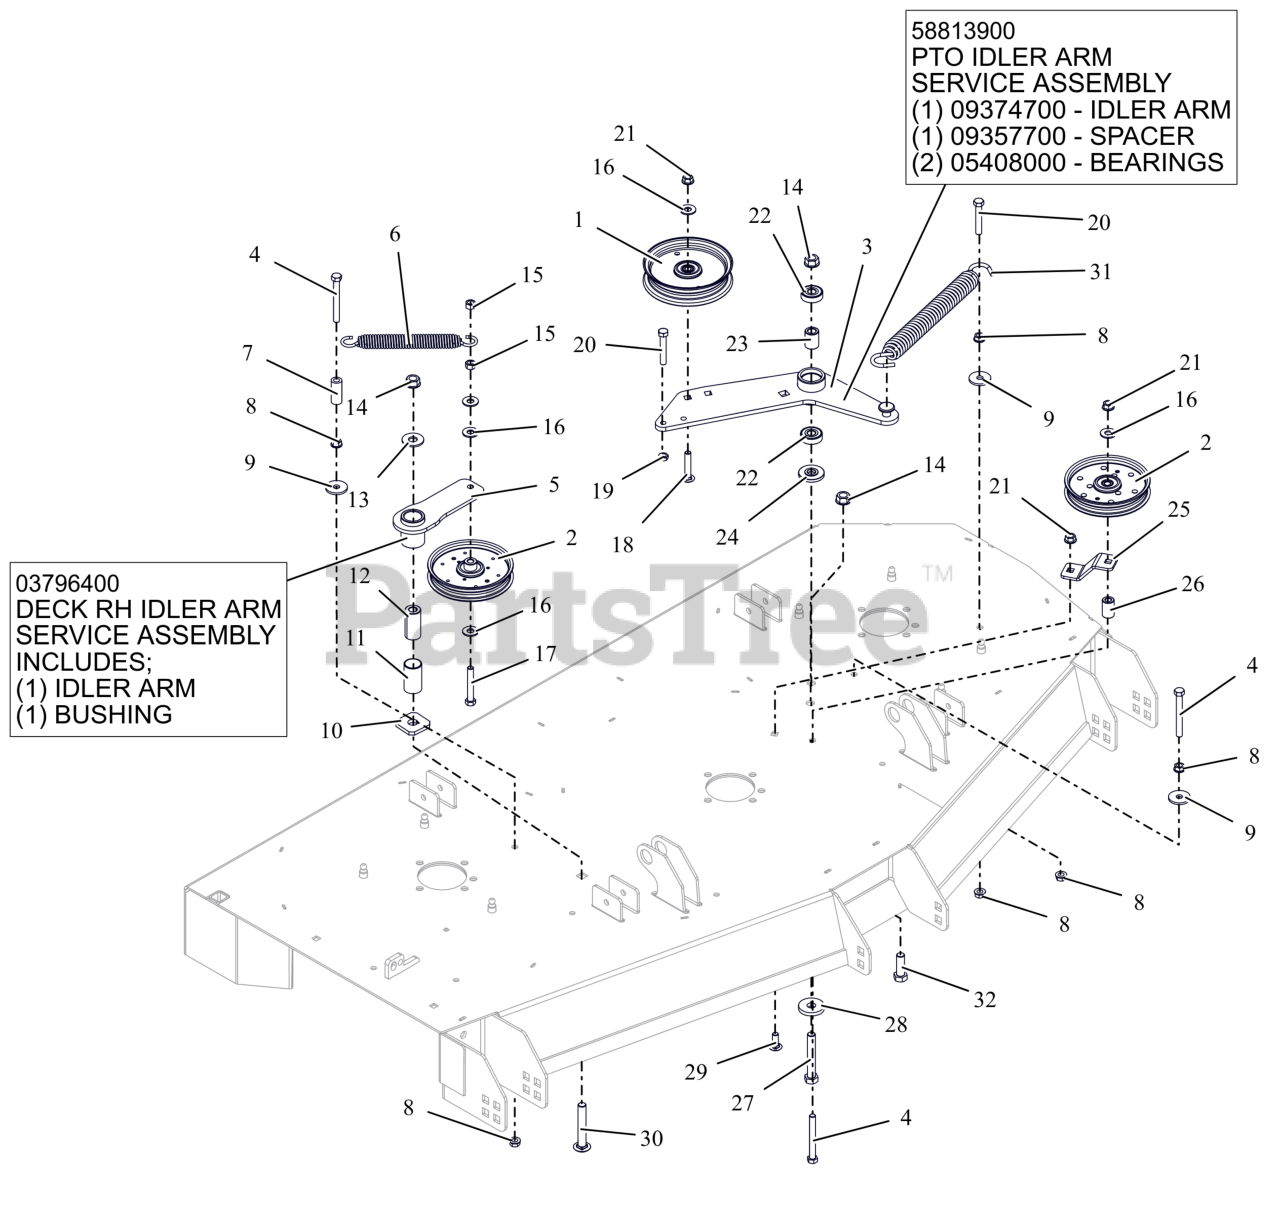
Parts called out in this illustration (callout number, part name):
1	IDLER- FLAT - 5.00" X .75"
2	IDLER- 5" FLANGED
3	PTO IDLER ARM
3	WLDMT, IDLER ARM PT660
3	SPACER .510 X .867 X 1.1485
3	BRG-BALL .500X1.38X.437
4	BLT, HEX .38-16X3.25 G5 ZCC
5	ASM, IDLER ARM (DECK)
5	WMT, IDLER ARM - BLACK
5	BSHG, 1.00X1.125X1.937
6	SPRING- EXTENSION
7	HOSE, .38 X 1.65
8	NUT, SPNLK-FLG .38-16 G5 ZCC
9	WSHR,FLT .406X1.375X.135 ZCC
10	WSHR-FLT .640X1.75X.250
11	BSHG, 1.00X1.125X1.937
12	BSHG, SPCR .502X.997X2.03 PM
13	WSHR,FLT .563X1.375X.109 ZCC
14	NUT-LK-CTR-FLG .500-13 GG ZCC
15	NUT-LK-CTR .38-16 ZC120
16	WSHR,FLT .438X1.00X.083 ZCC
17	BLT, HEX .38-16X2.50 G5 ZCC
18	BLT,RHSSN.375-16X2.00 G5 ZCC
19	NUT-JAM .375-16 G2 ZCC
20	BLT,HEX .38-16X2.25 G5 ZCC
21	NUT-LK-CTR-FLG .375-16 GF ZCC
22	BRG-BALL .500X1.38X.437
23	SPACER .510 X .867 X 1.1485
24	SPACER, IDLER ARM
25	PTO FIXED IDLER MTG BRKT -RED
26	BUSHING, SLV .380X.750X1.190
27	BLT,HEX .50-13X3.25 G5 ZCC
28	WSHR-FL-STL 0.557X1.625X0.25 ZCC
29	BLT,RHSSN .38-16X1.00 G5 ZCC
30	BTL,RHSSN .500-13 X 3.25 G5 ZCC
31	SPRING, EXTENSION
32	BLT,HEX .50-13X1.50 G5 ZCC
